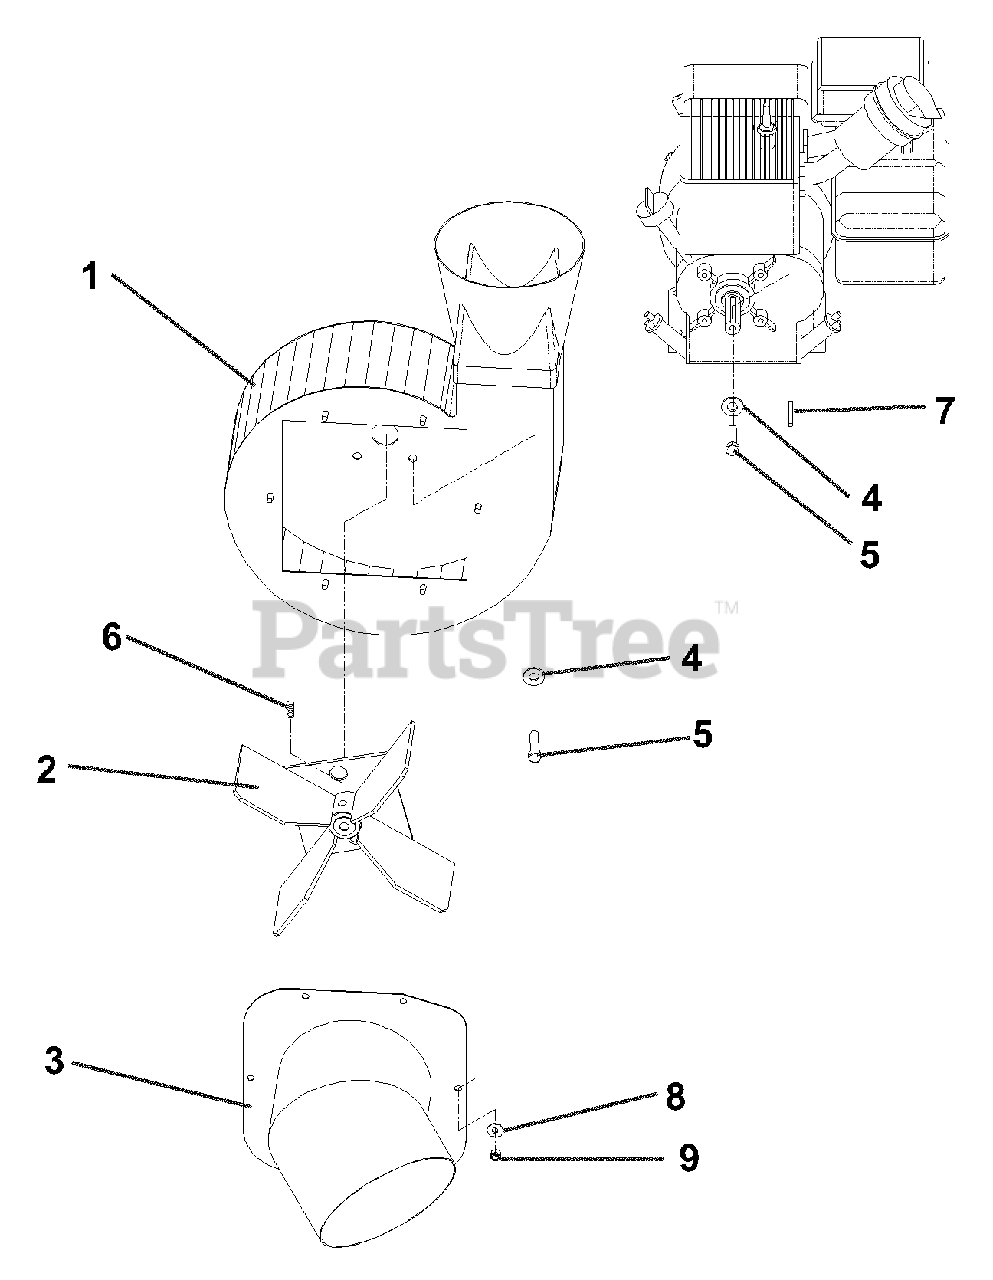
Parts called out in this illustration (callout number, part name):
1	Blower Housing
2	Impeller
3	Inlet, Blower Housing
4	Washer, Spring, 5/16"
5	Bolt, Hex, 5/16"-24 x 3/4"
6	Screw, Set, 3/8"-24 x 3/8"
7	Key, Square, 3/16" x 3/16" x 1-3/4"1
8	Nut, Hex, Nylon Lock, 1/4"-20
9	Washer, Flat, 1/4"
